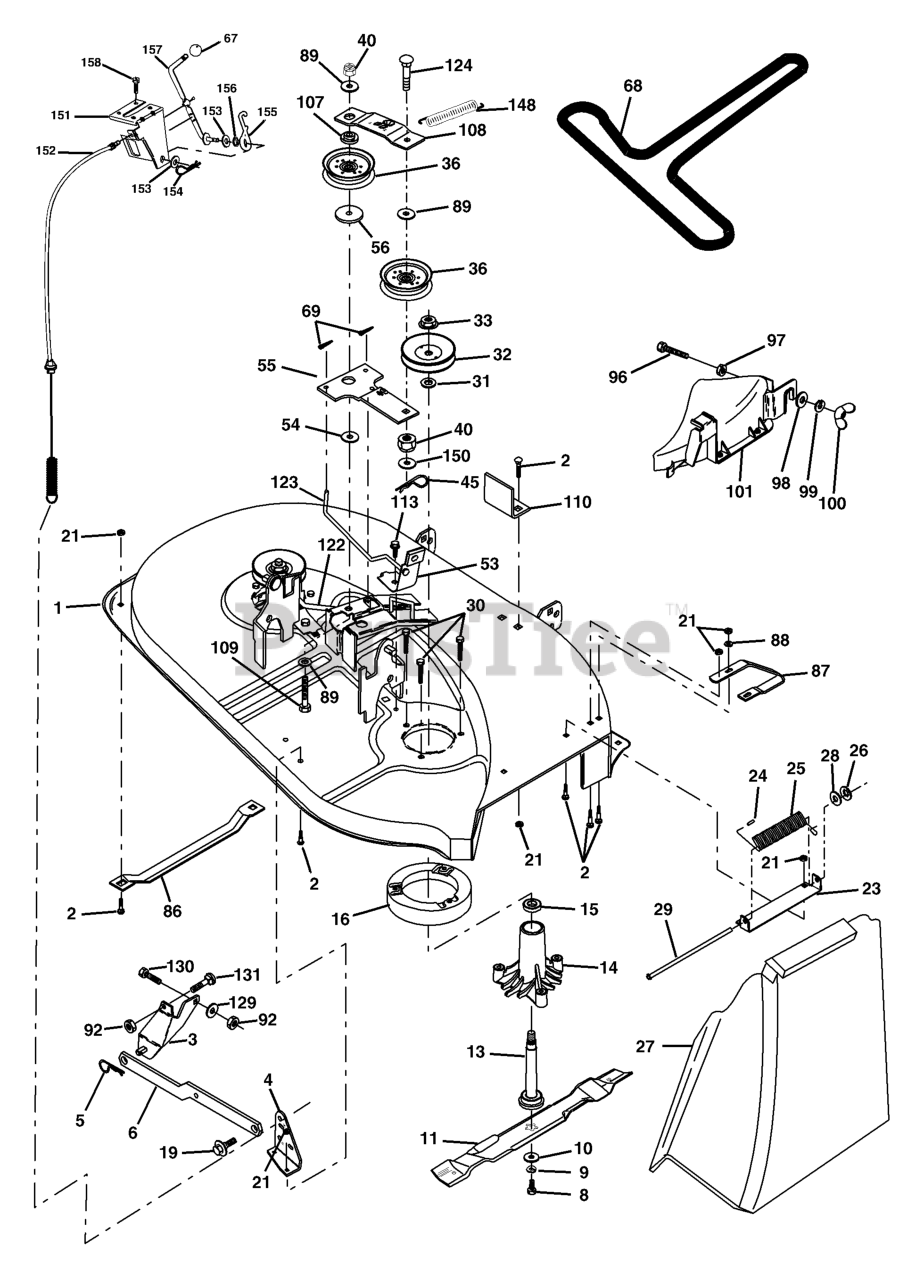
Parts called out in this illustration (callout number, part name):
1	MOWER HOUSING ASM
2	RP BOLT 5/16-18 X3/4 ZN/YEL GR
3	BRKT ASM SWAY BAR
4	BRACKET DECK SWAY BAR 38/42"
5	RETAINER-SPRNG RB
6	BAR SWAY DECK
8	BLADE BOLT
9	LOCKWASHER
10	WASHER.BLADE
11	BLADE 38" V MULCH
11	BLADE 38" V. MULCH
11	BLADE.HI.LIFT.38"
13	SHAFT ASM VENT
14	HOUSING.MANDREL.VENTED (MACHD)
16	STRIPPER.MANDREL.ROUND.BLACK
19	BOLT SHD 5/16-18
21	LOCKNUT
23	BRACKET, DEFLECTOR
24	CAP-SLEEVE LT
25	SPRING TORSION
26	NUT PUSH M
27	SHIELD, DEFLECTOR
28	Washer 11/32 x 5/8 x 16 Ga.
29	ROD-HINGE T
30	SCREW, WASHER HEAD
31	WASHER
32	PULLEY MANDREL
33	NUT, FLG TOPLOCK 9/16"
36	FLAT IDLER PULLEY
45	RETAINER M
53	BRAKE ASSEMBLY
55	IDLER ARM
56	SPACER.RETAINER.MOWER
67	KNOB T (3/8 HOLE)
68	V-BELT TRIPATH
69	COTTER PIN
86	RUNNER-LH M
87	RUNNER.RH.38
88	WASHER M
89	WASHER GT
92	NUT
96	LOCKNUT
97	Bolt 3/8-16 x 1-1/4
98	WASHER
99	WASHER, LOCK 3/8
101	COVER.MULCHING.38" (2 2)
107	SPACER.IDLER.ARM
108	STIFFENER.IDLER.ARM
109	Bolt Hex Fin 3/8-16 Unc x 2-1/2
110	UPSTOP DECK FRONT 38"
113	SCREW 5/16"
122	BRAKE ROD LH
123	ROD.BRAKE.MANDREL.RH
129	WASHER
130	BOLT
131	BOLT D
146	BOLT, CARRIAGE IDLER
148	IDLER RETURN SPRING
149	SPRING.RETAINER.YELLOW.ZINC
150	WASHER PM
151	BRACKET.CLUTCH.CABLE
152	CLUTCH CABLE 38"/46"
153	WASHER FLAT 3/8"
154	SPRING RETAINER
155	SPRING RETENTION LEVER
156	SPACER.CLUTCH.CABLE
157	ROD CLUTCH CABLE 3/8"
158	SCREW
